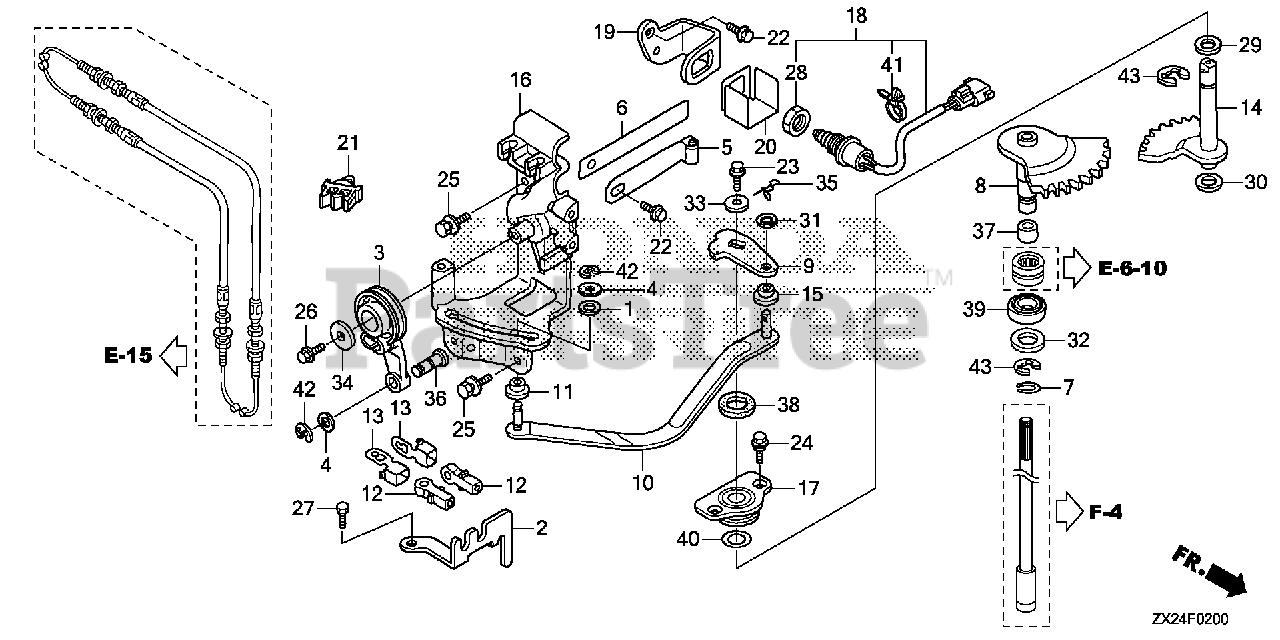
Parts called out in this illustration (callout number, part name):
1	WASHER, AIR CLEANER COVER SETTING
3	ARM, THROTTLE
4	WASHER, PIVOT
5	SPRING, CLICK
6	SPRING, CLICK ASSIST
7	RING, STOPPER
8	SHAFT, SHIFT (A)
9	ARM, SHIFT
11	COLLAR, SHIFT SLIDER
14	SHAFT, SHIFT (B)
15	BUSH, SHIFT ARM
16	BRACKET, SHIFT LINK
17	HOLDER, SEAL
18	SWITCH ASSY., NEUTRAL
19	BRACKET, NEUTRAL SWITCH
20	COVER, NEUTRAL SWITCH
21	CLIP, BRAKE PIPE
22	BOLT, FLANGE (6X14) (CT200)
22	BOLT, FLANGE (6X14)
23	BOLT, FLANGE (6X16)
24	BOLT, FLANGE (6X11)
25	BOLT-WASHER (6X16)
26	BOLT, FLANGE (6X12)
27	BOLT, HEX. (6X16)
28	NUT, HEX. (20MM)
29	WASHER, THRUST (14MM)
30	WASHER B, THRUST (14MM)
31	WASHER, PLAIN (6MM)
33	WASHER, PLAIN (6MM)
34	WASHER, PLAIN (6MM)
35	PIN, SNAP (6MM)
37	RING (INNER) (15X20X13)
38	OIL SEAL (14X26X6)
39	SEAL, WATER (14X26X8)
40	O-RING (26.9X2.4) (NOK)
41	CLIP, HARNESS BAND (145MM) (BLACK)
42	E-RING (4MM)
43	E-RING (12MM)
